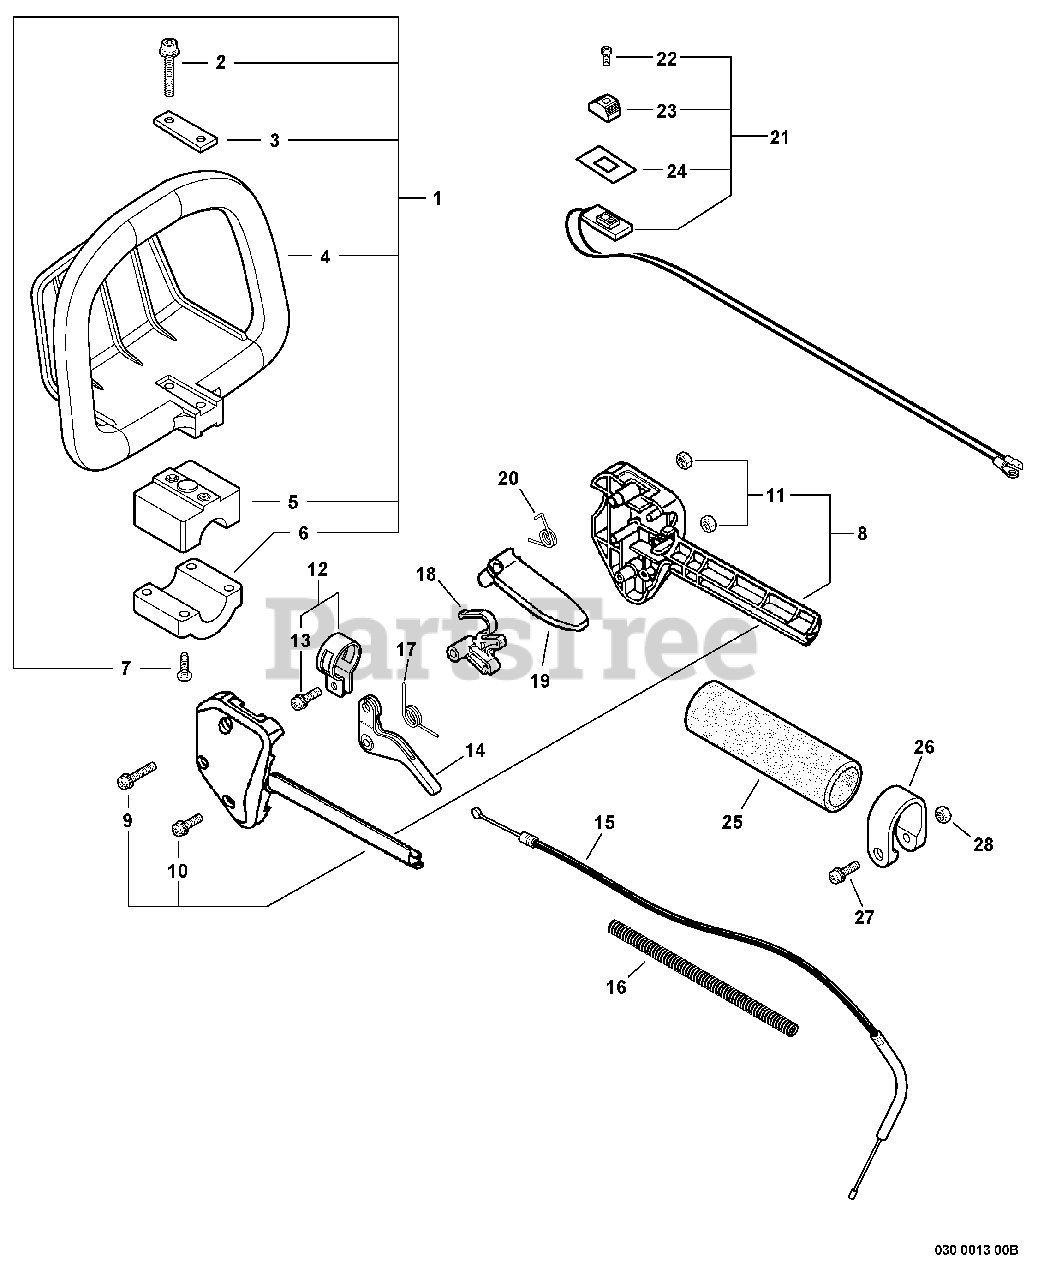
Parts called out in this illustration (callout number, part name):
1	HANDLE ASSY - FRONT
2	SCREW - 5X30
4	HANDLE - FRONT
5	BRACKET, HANDLE - UPPER
6	BRACKET, HANDLE - LOWER
7	SCREW - 5
8	THROTTLE BRACKET SET
9	SCREW - 5X35
10	SCREW - 5X25
12	CLAMP KIT
13	SCREW - 5X14
14	TRIGGER, THROTTLE
15	CABLE, THROTTLE
16	TUBE, PROTECTIVE - CORRUGATED
17	SPRING, TRIGGER
18	LOCKOUT, THROTTLE
19	LEVER, TRIGGER LOCKOUT
20	SPRING, LOCKOUT LEVER
21	IGNITION SWITCH ASSY
22	SCREW - 3X10
23	KNOB, SWITCH - ORANGE
24	COVER, SWITCH - STOP
25	GRIP, HANDLE - REAR
27	SCREW - 5X28
